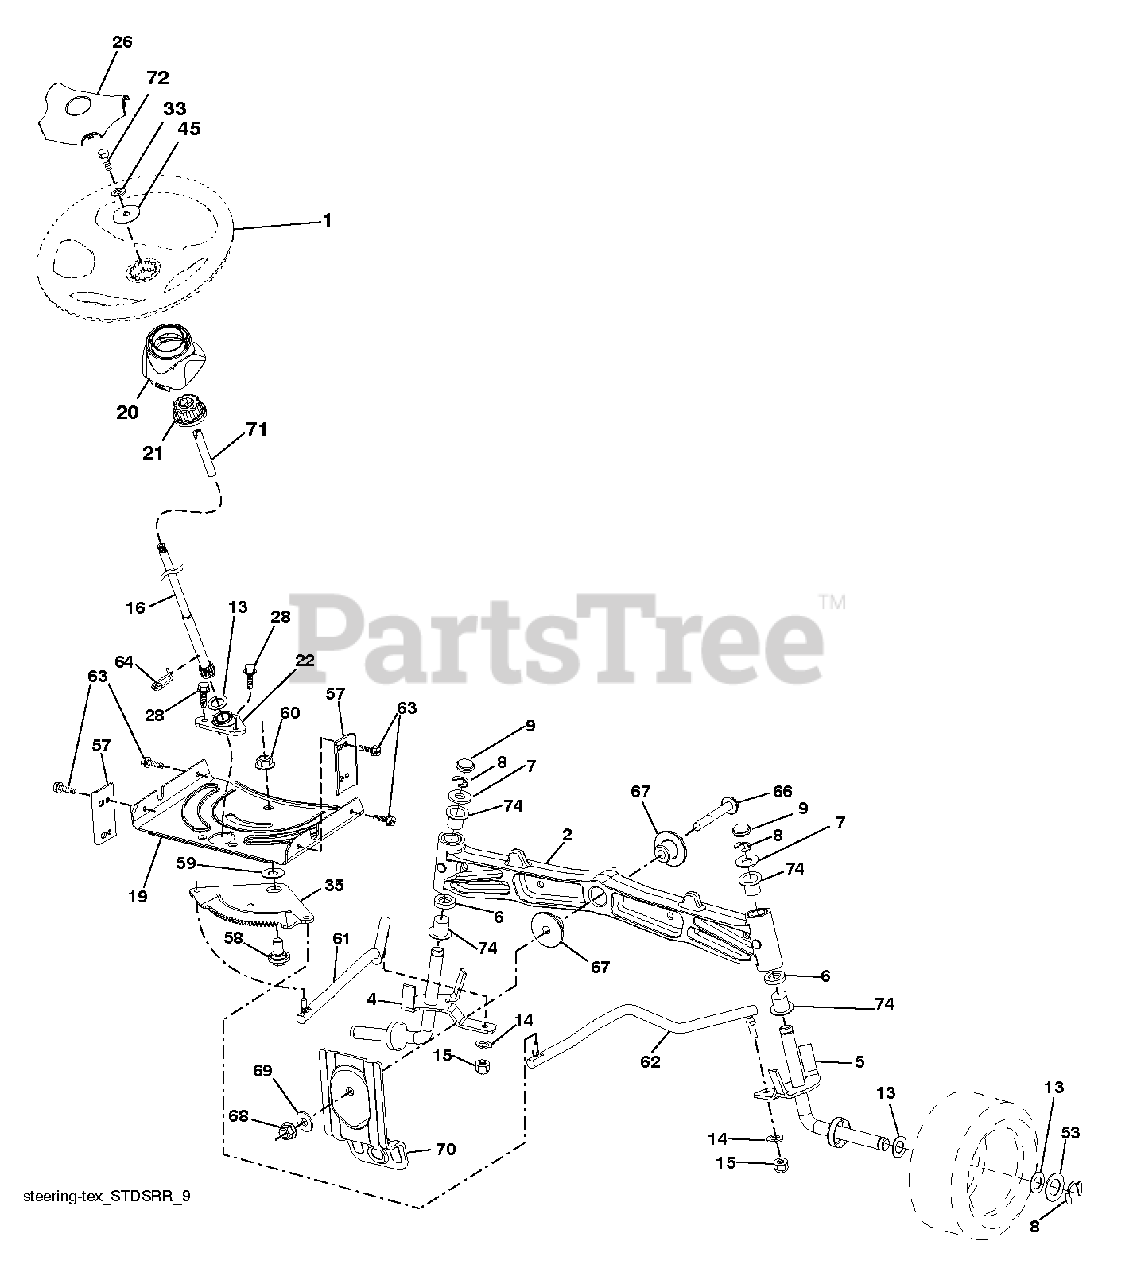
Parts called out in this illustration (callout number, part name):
1	WHEEL.STEERING.PREM.2.BLK
2	AXLE HALF ASM-WELDED
8	RING CLIP
9	CAP.SPINDLE
14	WASHER, LOCK 3/8
15	NUT CROWNLOCK 3/8-24
16	SHAFT.STEER.3/4.PLATED.TEX
19	PLATE.STEER.DDL.NLT/NG
20	BOOT.STEERING.PREDATOR.LT.BLAC
21	ADAPTER, WHEEL STNG..
22	STEERING.SUPT.LOWER.
26	INSERT.CAP.STRG.WH.BLACK
28	SCREW, 3/8-16X3/4
33	LOCKWASHER
35	GEAR.SECTOR.PLATE.DDL.
45	WASHER.11/32
53	WASHER.HARDENED
57	BRACKET.UPSTOP.TEX
58	BOLT.SHOULDER.SECTOR.P
59	WASHER.THURST.SECTOR.S
60	NUT FLANGE LOCK 5/8-11
61	DRAGLINK.LH.BALLSTUD.D
62	DRAGLINK.RH.BALLSTUD.D
63	SCREW
64	RETAINER.CLIP.SPRING.S
66	BOLT HEX FGHD 7/16-14 X 3 SERR
67	BUSHING.PM.FRONT AXLE
68	NUT.LOCK.FLANGE.7/16
69	WASHER.1.5X.505X.118
71	SHAFT.EXTEN.STRG.SPLINE
72	BOLT 5/16-18 X 4 W/PATCH
74	BRNG T
